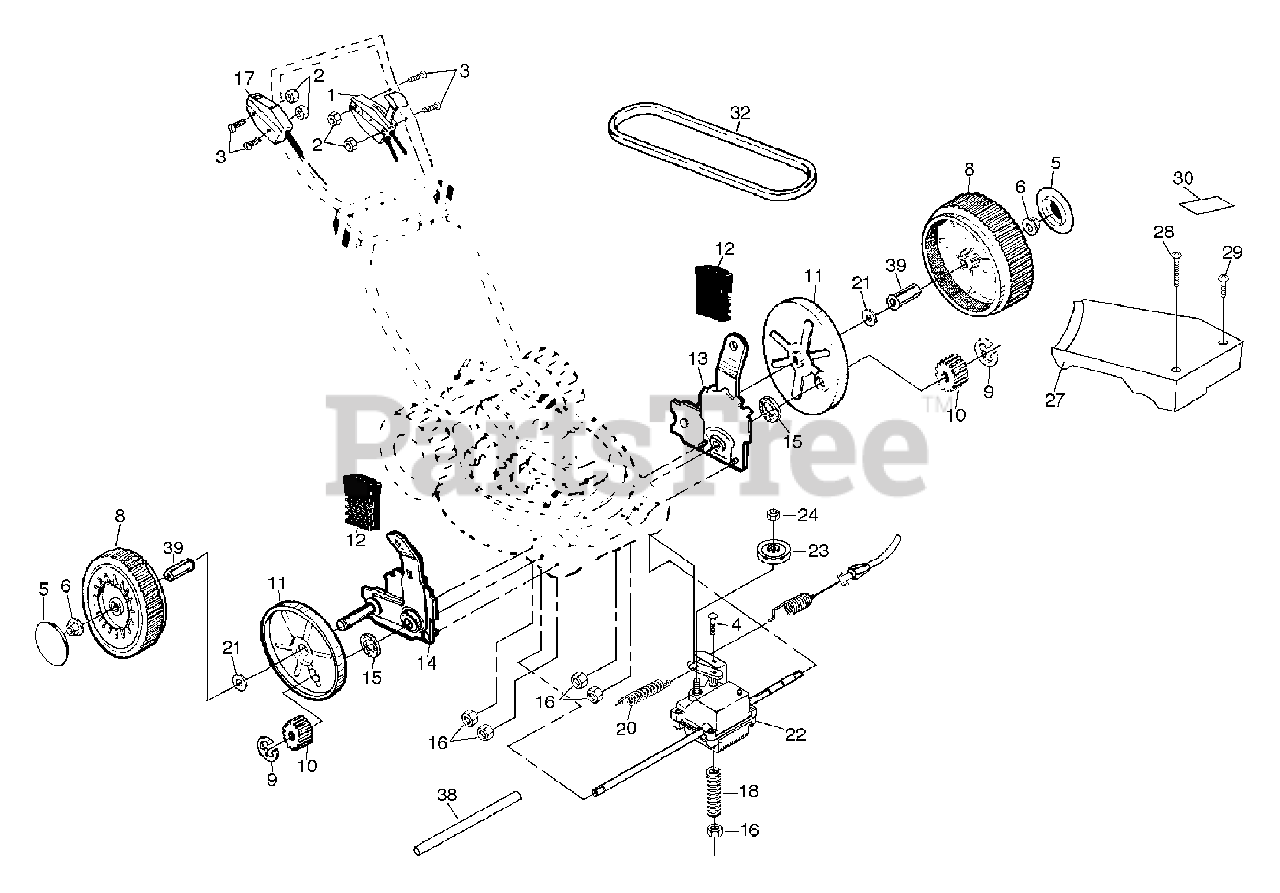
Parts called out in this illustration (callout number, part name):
1	Drive Control
2	Locknut 1/4-20
3	Hex Washer Head Screw 1/4-20 x 2-1/8
4	Carriage Bolt 1/4-20 x 2
6	Flanged Locknut
8	Wheel & Tire Assembly
11	Dust Cover
12	Selector Knob
13	Wheel Adjuster Assembly (Left)
14	Wheel Adjuster Assembly (Right)
15	Felt Washer
16	Locknut 1/4-20
17	Engine Zone Control Cable
22	Gear Case Assembly
23	Drive Pulley
24	Locknut
27	Drive Cover
28	Pan Head Machine Screw #10-24 x 2-3/4
29	Pan Head Machine Screw #10-24 x 1-3/4
30	Drive Cover Decal
32	V-Belt
38	Drive Shaft Cover
39	Wheel Bushing
